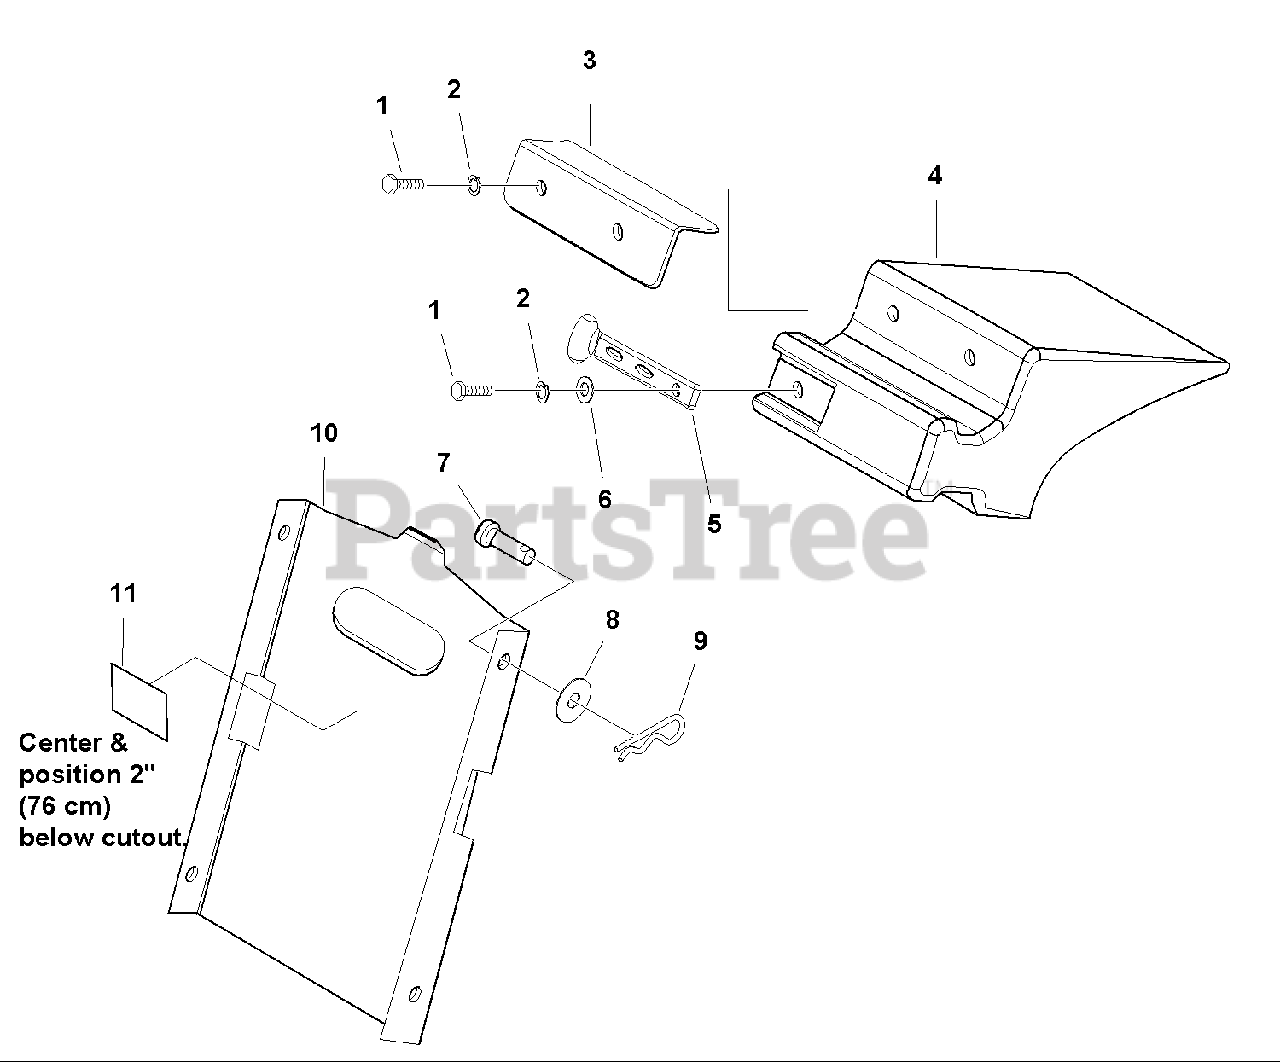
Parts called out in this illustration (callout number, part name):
1	CAPSCREW, Hex Head, 1/4-20 x 3/4
2	LOCKWASHER, 1/4
3	BRACKET, Mulching Plug
4	PLUG, Mulching
5	STRAP, Hood, Black Rubber
6	WASHER, 1/4
7	PIN, Clevis
8	WASHER, 5/16
9	CLIP, Hair Pin
10	GUARD & DEFLECTOR ASSEMBLY
11	DECAL, Danger
